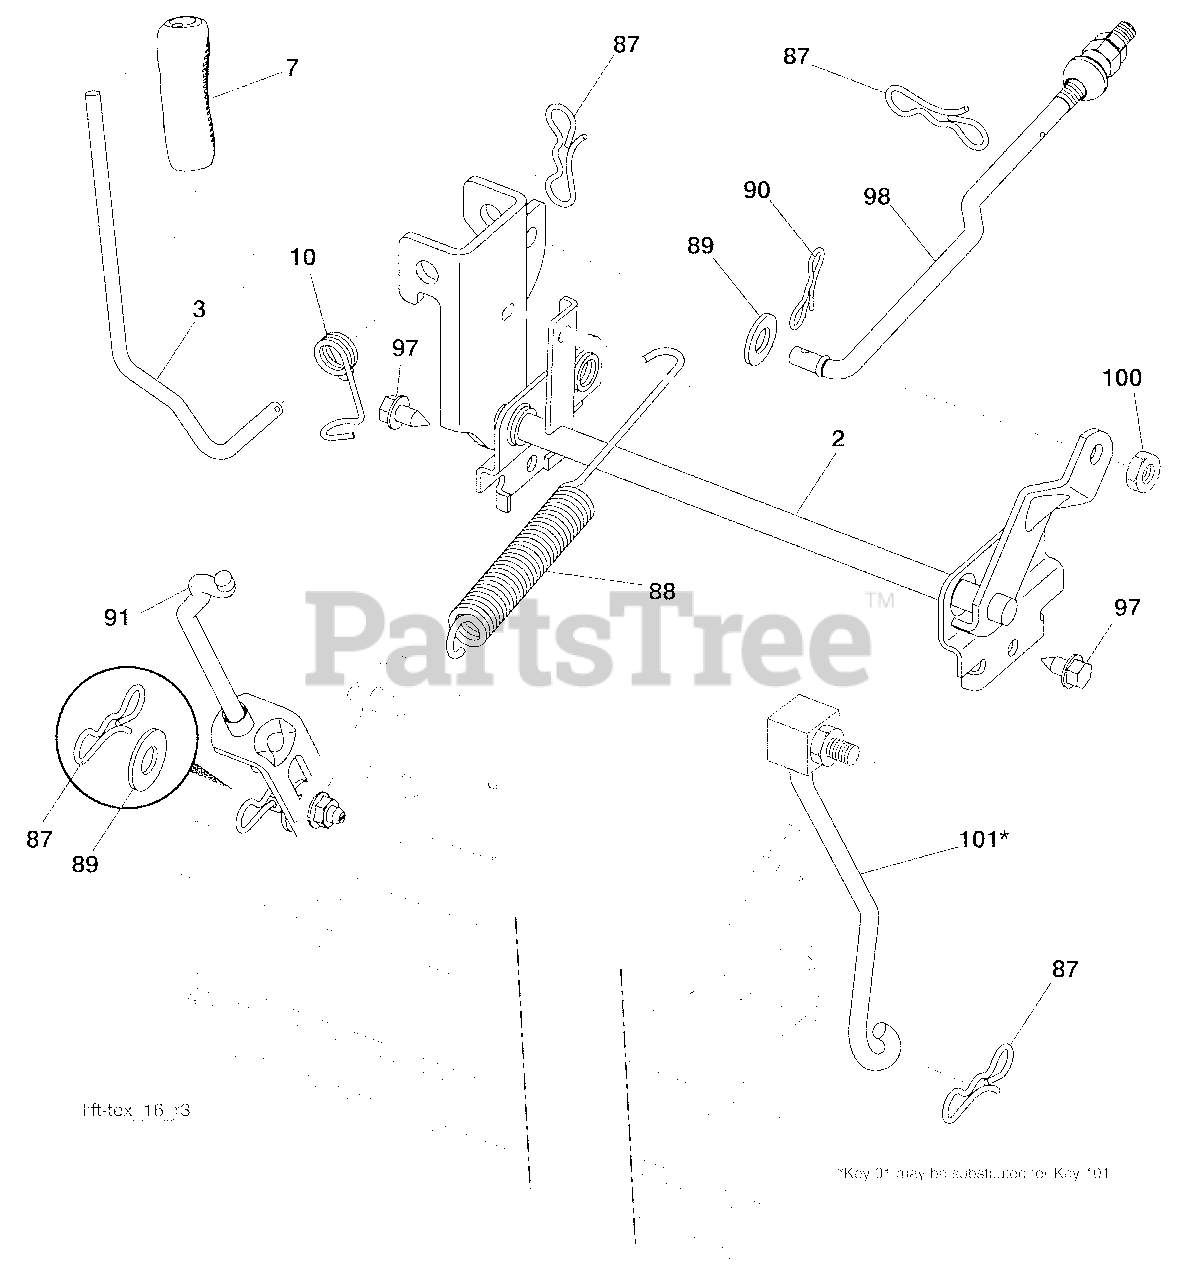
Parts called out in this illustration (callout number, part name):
2	Shaft Asm., Lift
3	Lever Asm., Lift RH
7	Grip, Lever
10	Spring Torsion
87	Pin Cotter 7/16 Bow Tie Lock
88	Spring Lift Assist
89	Washer Clear Zinc
90	Pin Cotter 5/16 Bow Tie Lock
91	Link Lift Susp Mower Rear
97	Screw 3/8-16 x 3/4
98	Link Lift Susp. Front Mower
100	Nut Center Lock 3/8-16 unc
101	Link Asm. Lift FXD
